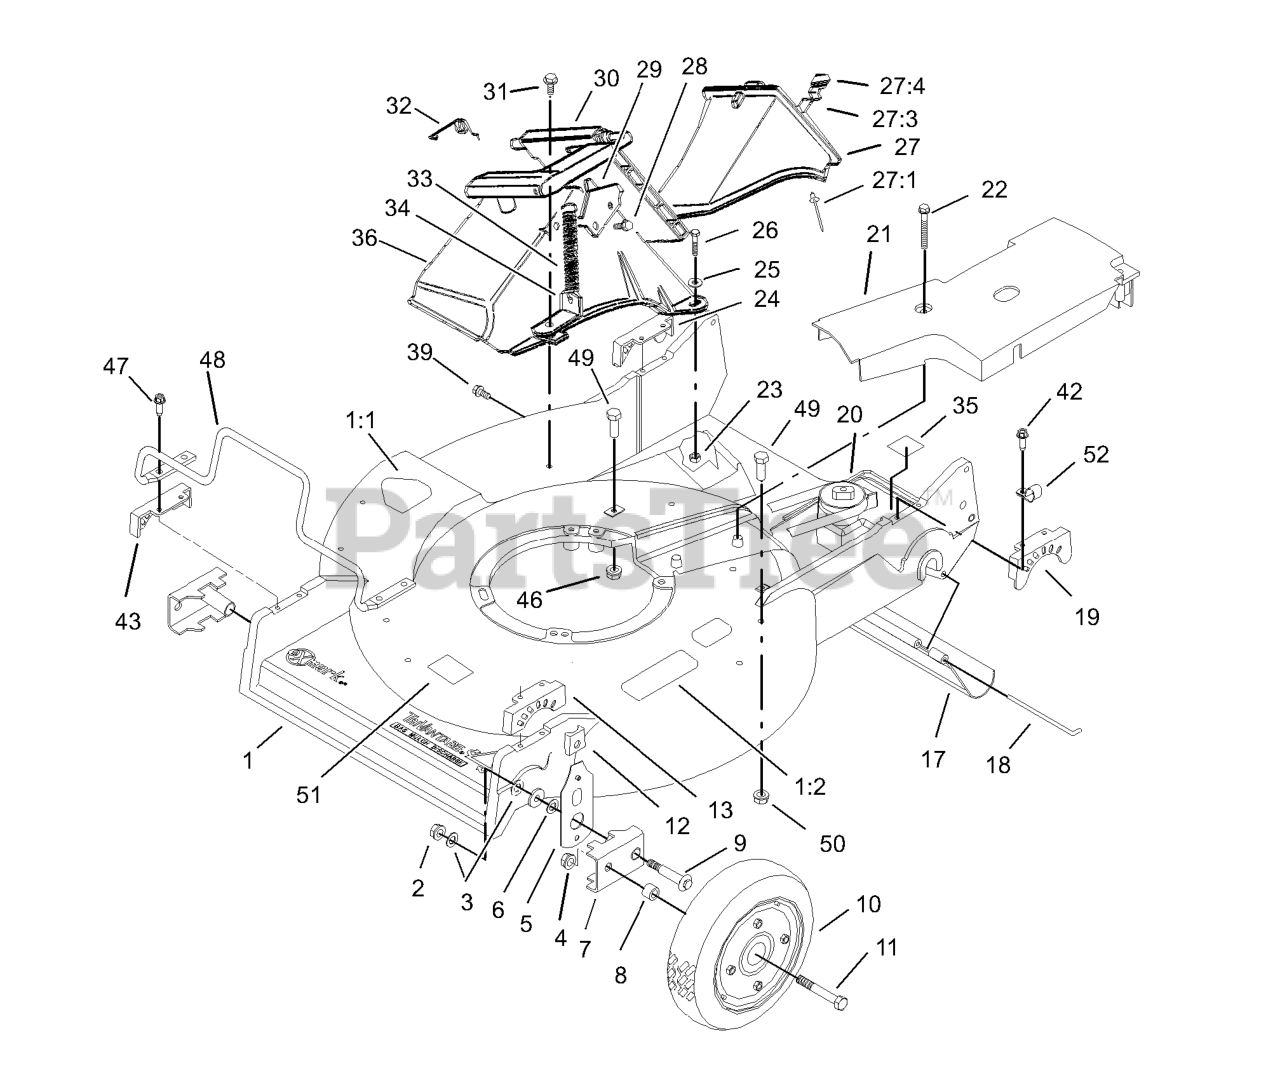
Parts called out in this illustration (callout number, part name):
1:1	DECAL-DANGER
1:2	DECAL-WARNING
2	NUT-LOCK
4	NUT-LOCK, CONE
5	FRONT SPRING ARM ASM
6	WASHER-THRUST
7	ARM-PIVOT, FRONT
8	SPACER-WHEEL
11	BOLT-CARR
12	KNOB-ARM
13	QUADRANT-FRONT, LH
18	ROD-SHIELD
19	QUADRANT-REAR, LH
21	COVER-BELT
22	SCREW-HWH
23	NUT-LOCK, NI
24	QUADRANT-REAR, RH
25	WASHER-FLAT
26	SCREW-HH
27	DISCHARGE PLUG ASM
27:1	RIVET-HEAD, FLAT
27:3	LATCH-PLUG, DISCHARGE
27:4	GRIP-LATCH
28	SCREW-PLASTITE
29	LATCH-PLATE
30	DISCHARGE DOOR ASM
31	SCREW-HWH
32	RETAINER-DOOR
33	SPRING-DOOR
34	BRACKET-SPRING
35	Label-Grease
36	TUNNEL-DISCHARGE
39	SCREW AND WASHER ASM
42	SCREW-HWHTF
43	QUADRANT-FRONT, RH
47	SCREW-HWHTF
48	GUARD-ENGINE
49	SCREW-HH
50	NUT-LOCK, NI
51	DECAL-BLADE
52	CLIP-CLOSED, INSULATED
